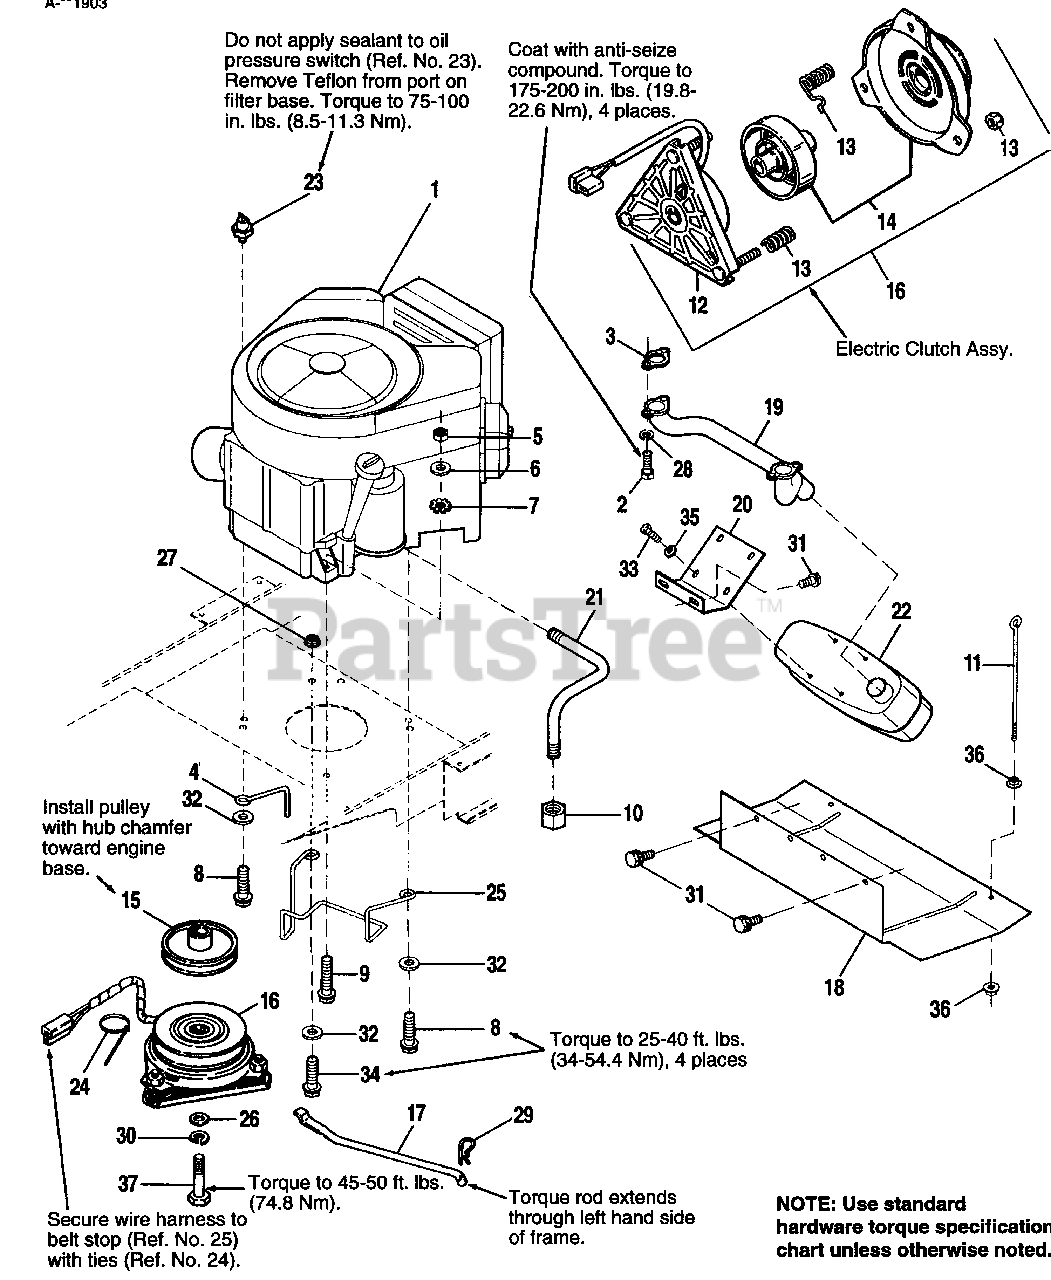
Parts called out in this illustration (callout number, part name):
1	ENGINE, 12.5 or 16 HP Briggs & Stratton
2	CAPSCREW, Metric
3	GASKET, Muffler
5	NUT, Hex, 3/8-16
6	LOCKWASHER, 3/8
7	LOCKWASHER, Ext. Tooth, 3/8
8	SCREW, Taptite, 3/8-16 x 1-1/2
9	SCREW, Taptite, 3/8-16 x 2-1/2
10	CAP, Hex, Pipe, 3/8
11	ROD, Hold Down
12	FIELD ASSY., Clutch
13	ACCESSORY KIT, Clutch
14	ROTOR ASSY/ARMATURE ASSY. KIT, Clutch
15	PULLEY ASSY., Drive
16	ELECTRIC CLUTCH ASSY., (Incl. Ref. Nos. 12-14)
17	ROD, Torque
18	SHIELD, Heat
19	MANIFOLD, Exhaust
20	BRACE, Muffler
22	MUFFLER ASSY., w/Deflector
23	SWITCH, Oil Pressure
26	WASHER, 7/16
27	NUT, Retainer, 5/15-18
28	LOCKWASHER, 5/8
29	CLIP, Hair Pin
30	LOCKWASHER, 7/16
31	SCREW, Taptite, 5/16-18 x 1/2
32	WASHER, 3/8
33	SCREW, Taptite, 1/4-20 x 5/8
34	SCREW, Hex, Whizlock, 5/16-18 x 3/4
35	WASHER,
36	NUT, Flange, Whizlock, 1/4-20
37	CAPSCREW, Hex, 7/16 x 3-1/4
